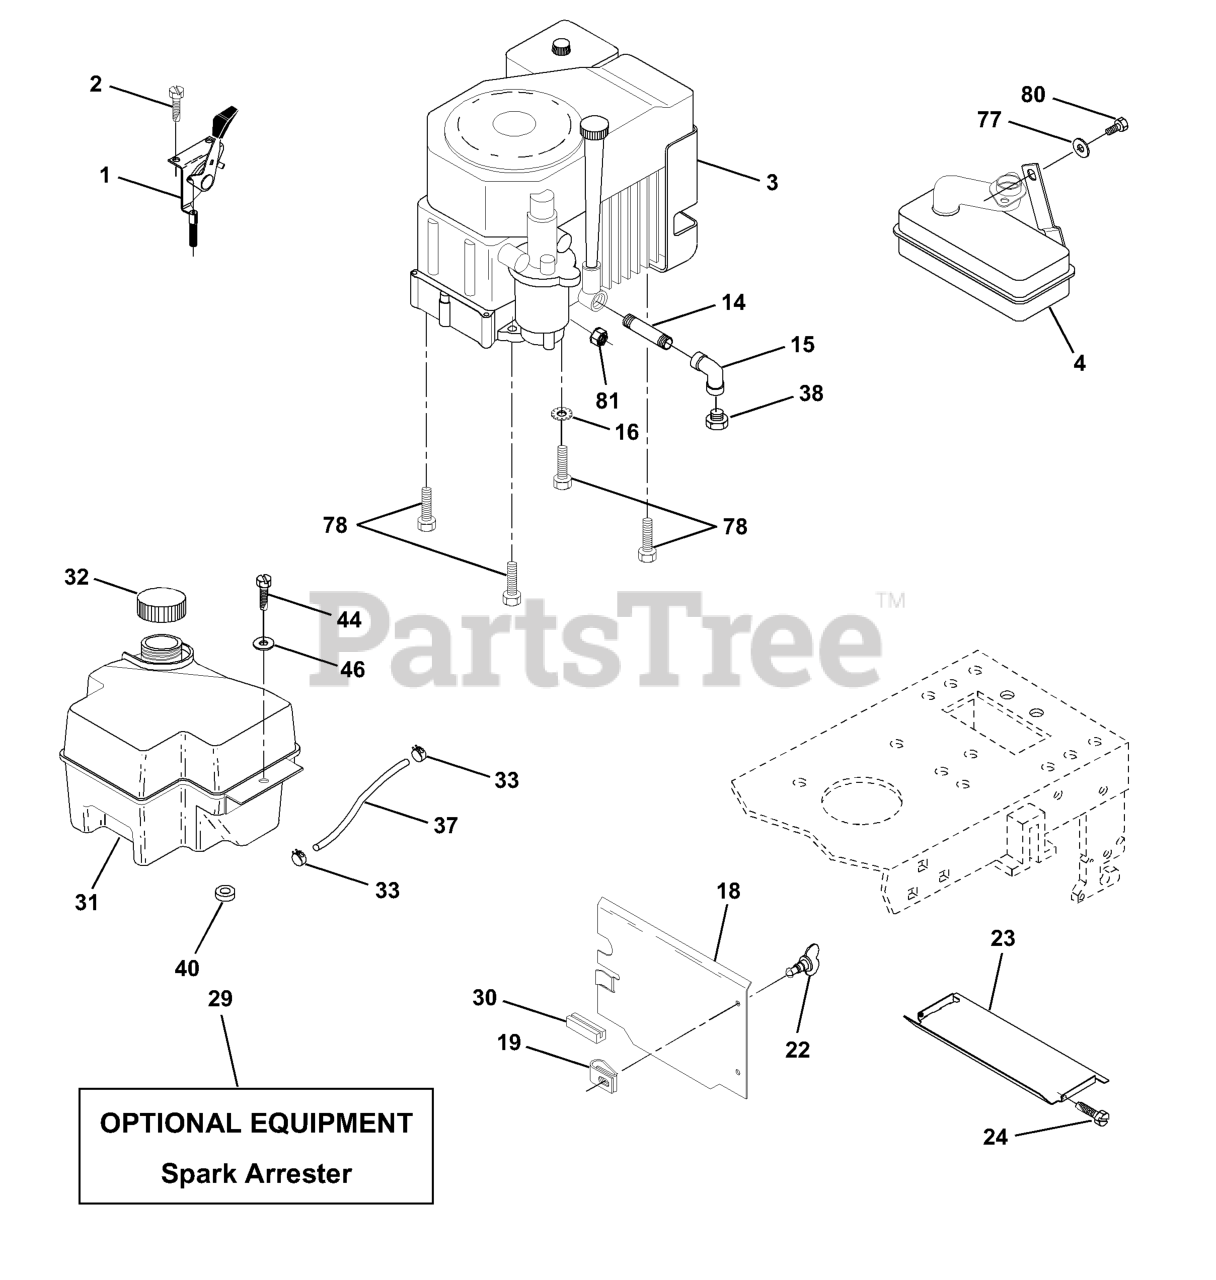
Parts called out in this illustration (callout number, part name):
1	CONTROL SWITCH 27 LH
2	SCREW LT
3	Engine Kohler, Model Number CV15S 13 HP
4	MUFFLER LT 12.5
14	Nipple Pipe 3/8 Npt X 3-1/2
15	ELBOW
16	WASHER EXT TOOTH LOCK 5/16
18	HEAT SHIELD
19	RECEPTACLE LT
20	RETAINER LT
21	WASHER
22	STUD 1/4 TURN
23	HEAT SHIELD
29	KIT.SPARK ARRESTOR 794945 B&S
30	RECEPTACLE LT
31	FUEL TANK
32	FUEL CAP
33	HOSE CLAMP
37	LINE.FUEL.20
38	Plug Oil Drain
40	BUSHING.SNAP.NYL.BLK.
44	SCREW HEX CRT
46	WASHER
77	WASHER
78	Bolt, Engine Mounting
80	Bolt Hex Hd 5/16-18 UNC x 1/2
81	NUT FLANGE 1/4-20 STARTER NUT
